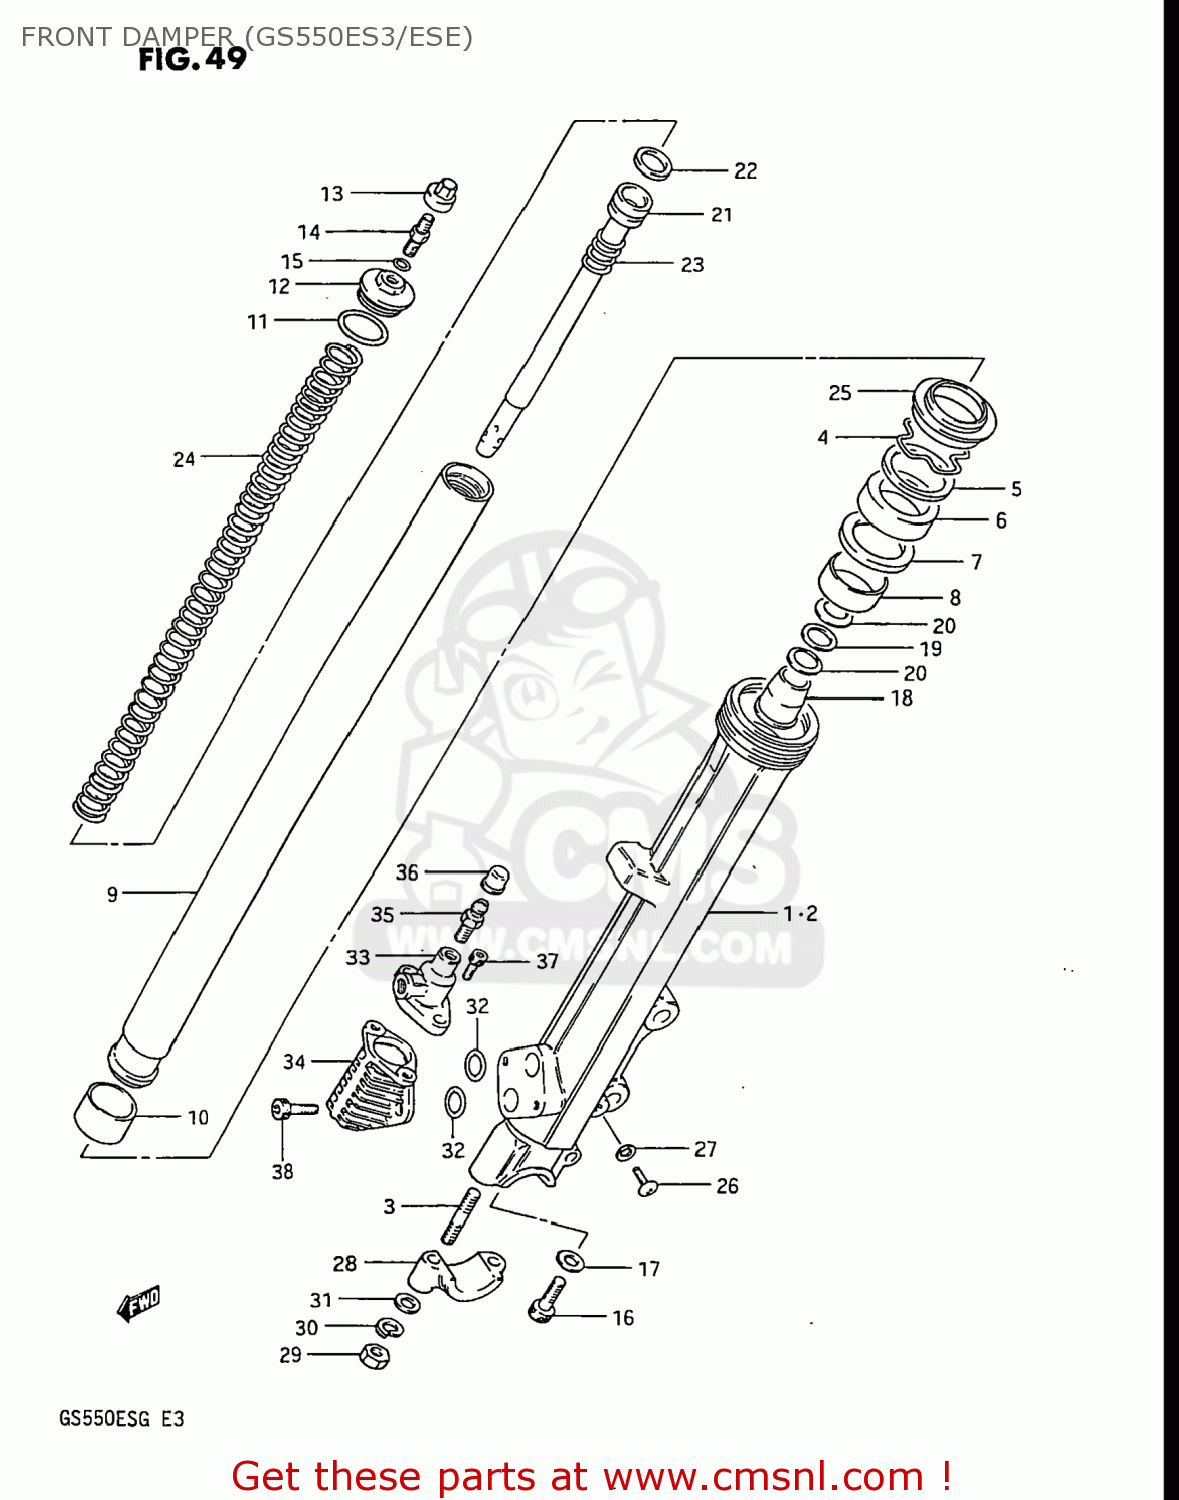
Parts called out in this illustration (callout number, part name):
1	TUBE,OUTER,RIGHT
2	TUBE,OUTER,LEFT
3	STUD 8X30
4	RING,STOPPER
5	WASHER. FRONT FORK
6	OIL SEAL,FRONT FORK
7	WASHER
8	METAL,SLIDE
9	TUBE,FORK,INNER
10	METAL,FRONT FORK PISTON
11	O RING
12	CAP
13	CAP,FRONT FORK AIR VALVE
14	VALVE,FRONT FORK AIR
15	O-RING
16	BOLT,FORK CYLINDER(10X25)
17	GASKET (NAS)
18	PIECE,OIL LOCK
19	WASHER
20	SPRING,LEAF
21	CYLINDER,FRONT FORK
22	RING,PISTON
23	SPRING,REBOUND
24	SPRING
25	SEAL,DUST
26	SCREW
27	GASKET,DRAIN,PLUG (NAS)
28	HOLDER,AXLE
29	NUT
30	WASHER,LOCK,8.
31	WASHER
32	O RING
33	PLUNGER SET
34	PDF ASSEMBLY
35	BREATHER,AIR
36	CAP,BREADER
37	BOLT
38	BOLT
